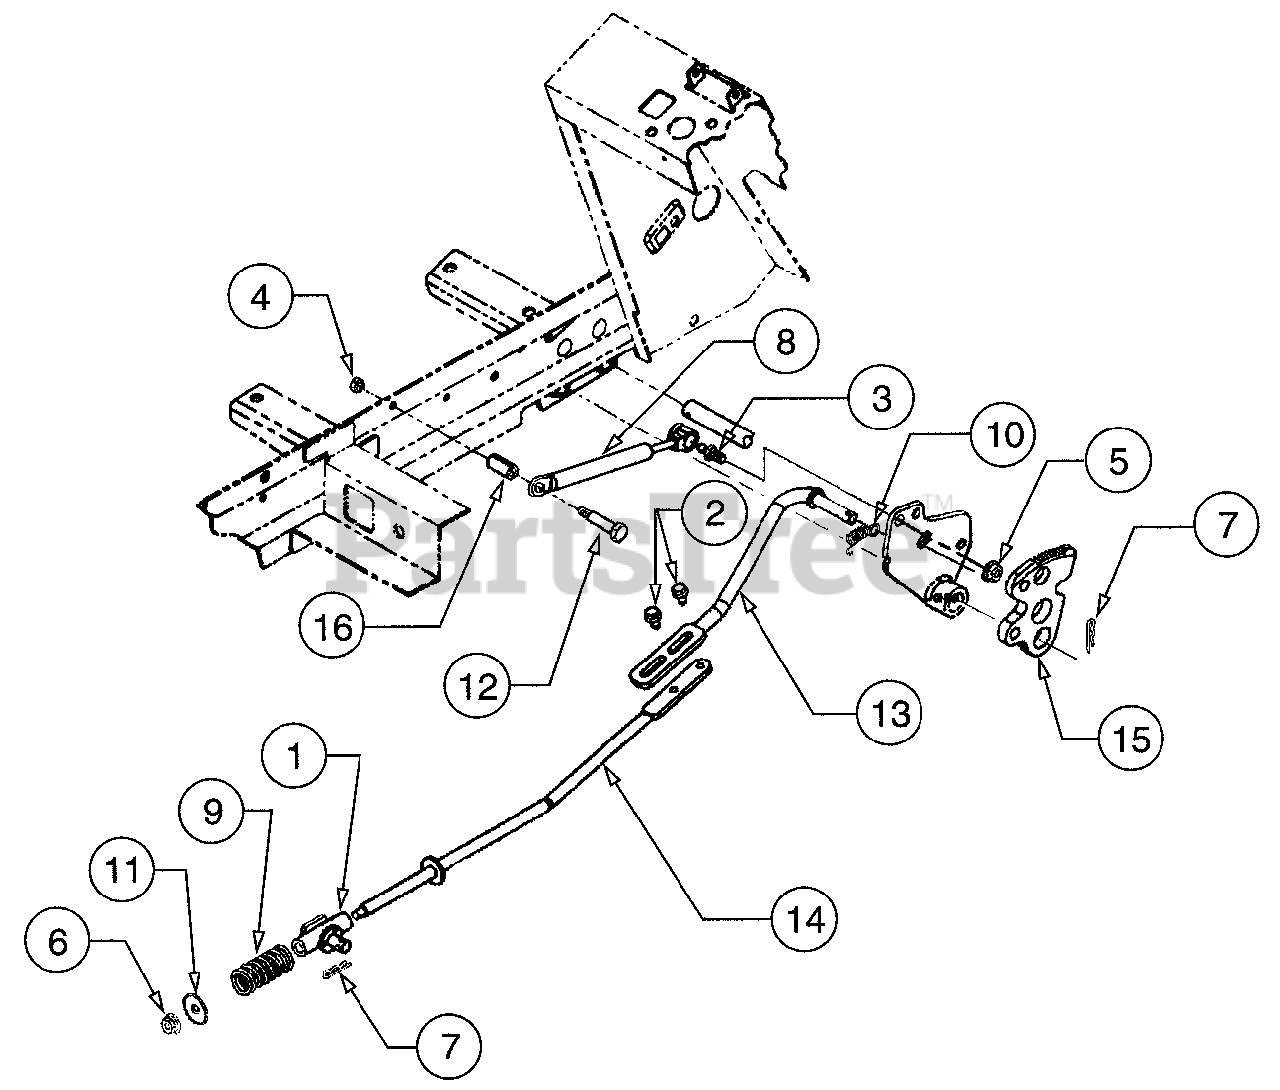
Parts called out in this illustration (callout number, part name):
1	Pivot Assembly
2	Screw, Hex Wsh Hd Tapp, 1/4-20 x .5
3	Screw, Ball, 5/16-18 x.56
4	Nut, Hex Sems, 1/4-20
5	Nut, Hex Flange Lock, 5/16-18 GR5
6	Nut, Hex Flange Lock, 1/4-20
7	Pin, Internal Cotter
8	Cylinder, Damper
9	Spring, Compression, .63 ID x 2
10	Spring, Extension, 3/8 OD x 1.44
11	Washer, Flat, .265 x 1 x .030
12	Bolt, Shoulder, .374 Dia x 1.375
13	Rod, Front Control
14	Rod, Rear Hydro Control
15	Plate, Cruise
16	Spacer, Split Tubing, .375 ID x 1.04
